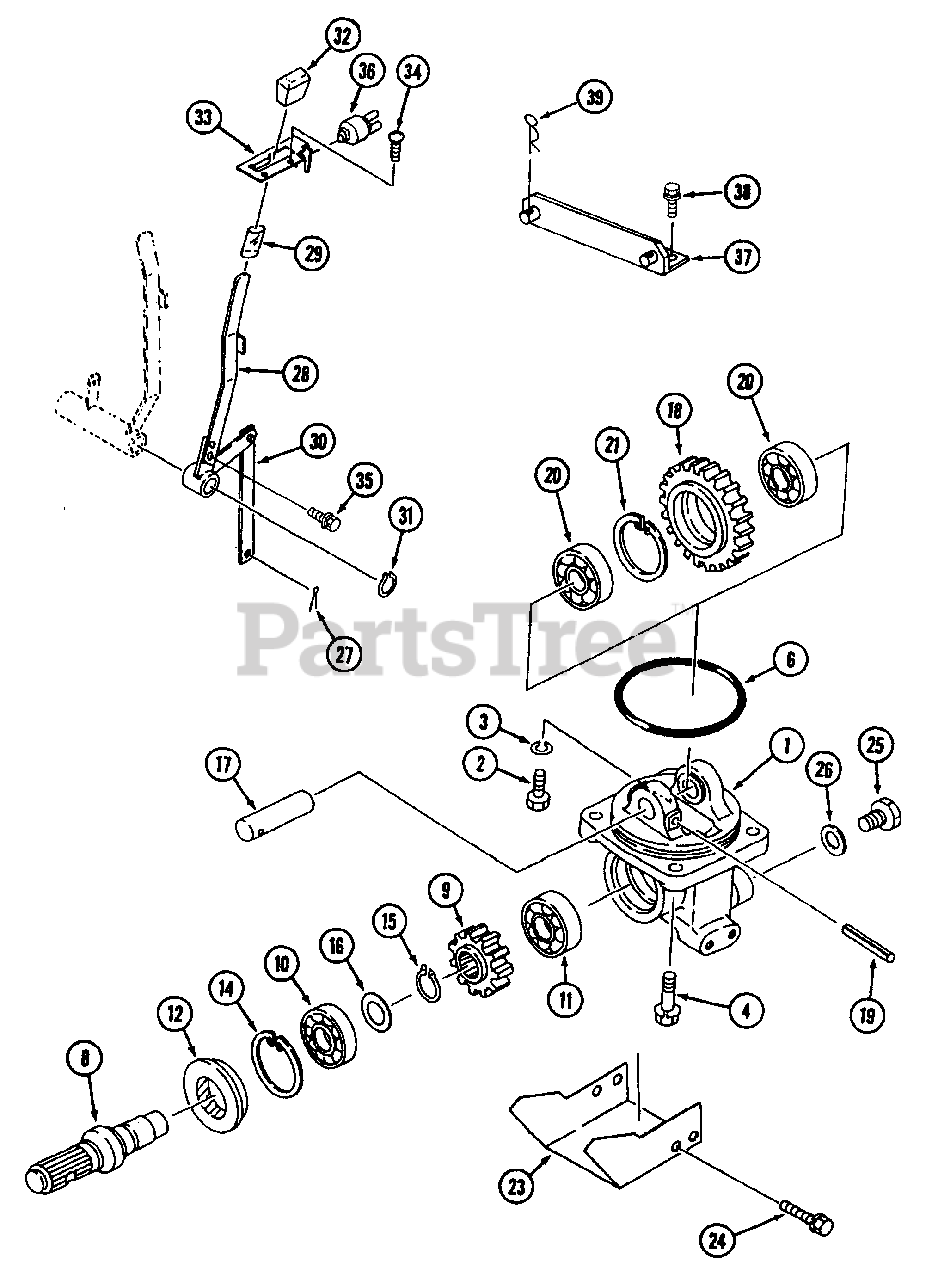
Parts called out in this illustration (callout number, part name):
1	Case, Mid PTO
26	Seal, Washer
27	Pin, Split
28	Lever, Mid PTO
30	Lever, Mid PTO
33	Plate, Mid PTO
37	Bracket, Drawbar
